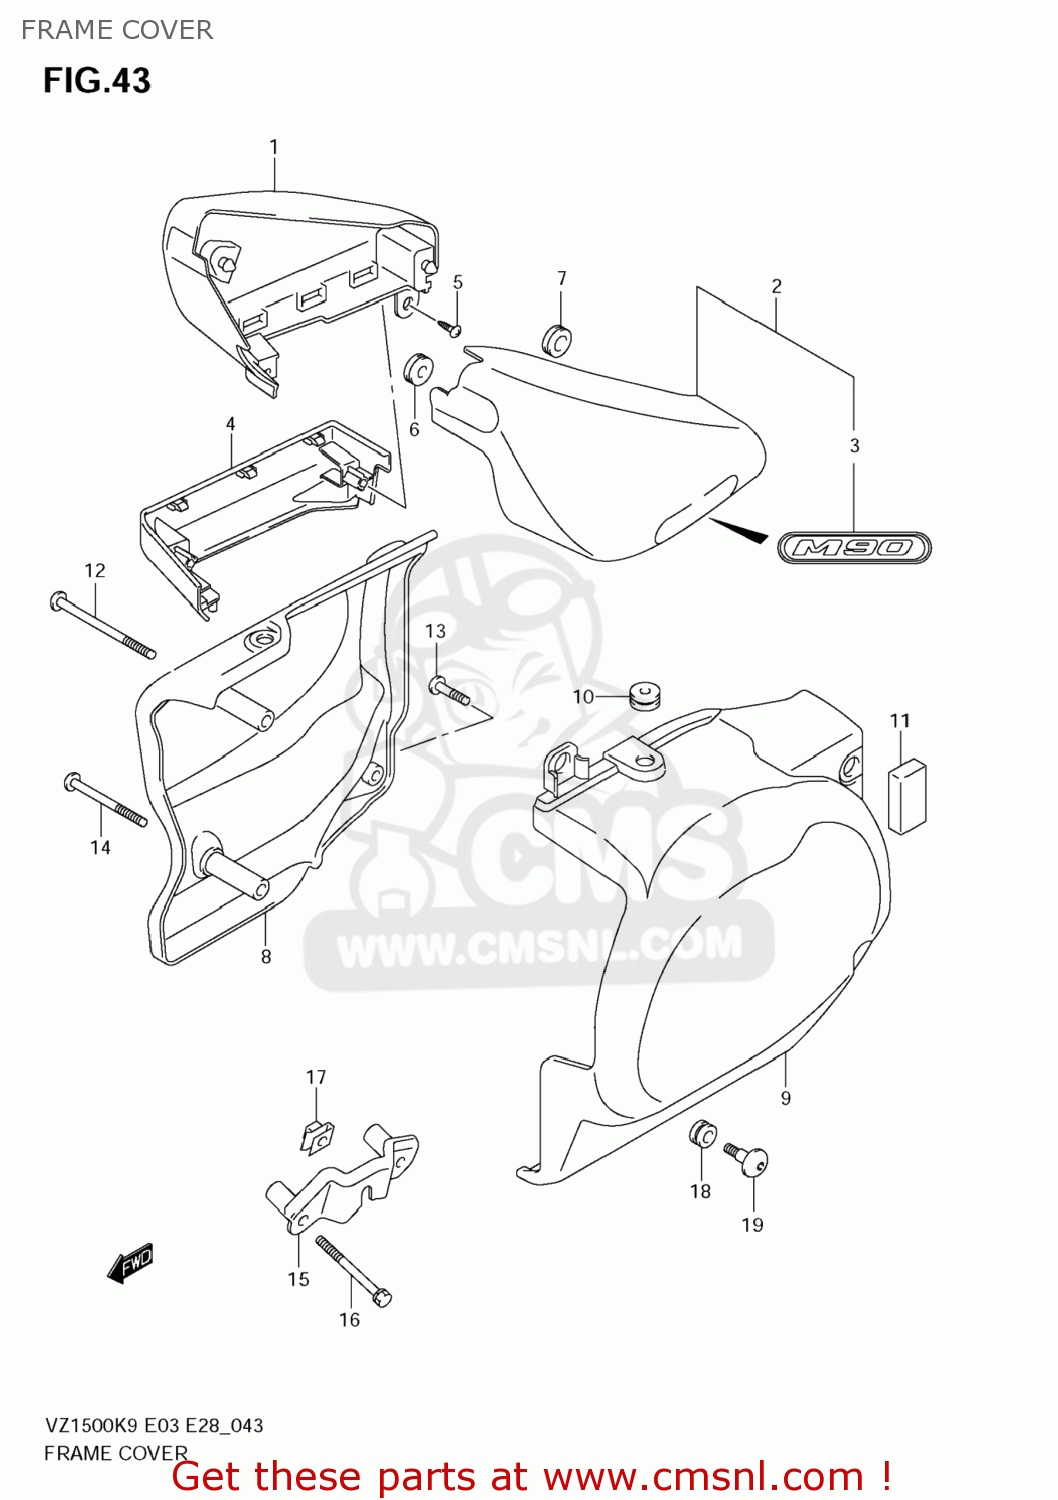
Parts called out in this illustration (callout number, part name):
1	COVER,SIDE,R(RED)
2	COVER,SIDE,L(RED)
3	EMBLEM,M90
4	COVER,SIDE LWR,R
5	SCREW
6	CUSHION
7	CUSHION
8	COVER,LWR,R
9	COVER,LWR,L
10	CUSHION
11	MUD GUARD,REAR FENDER
12	SCREW,LWR COVER,R FR UP
13	SCREW(6X20)
14	SCREW,LWR COVER,R FR LWR
15	BRACKET,LWR COVER,L
16	BOLT
17	NUT
18	CUSHION
19	SCREW(6X20)
